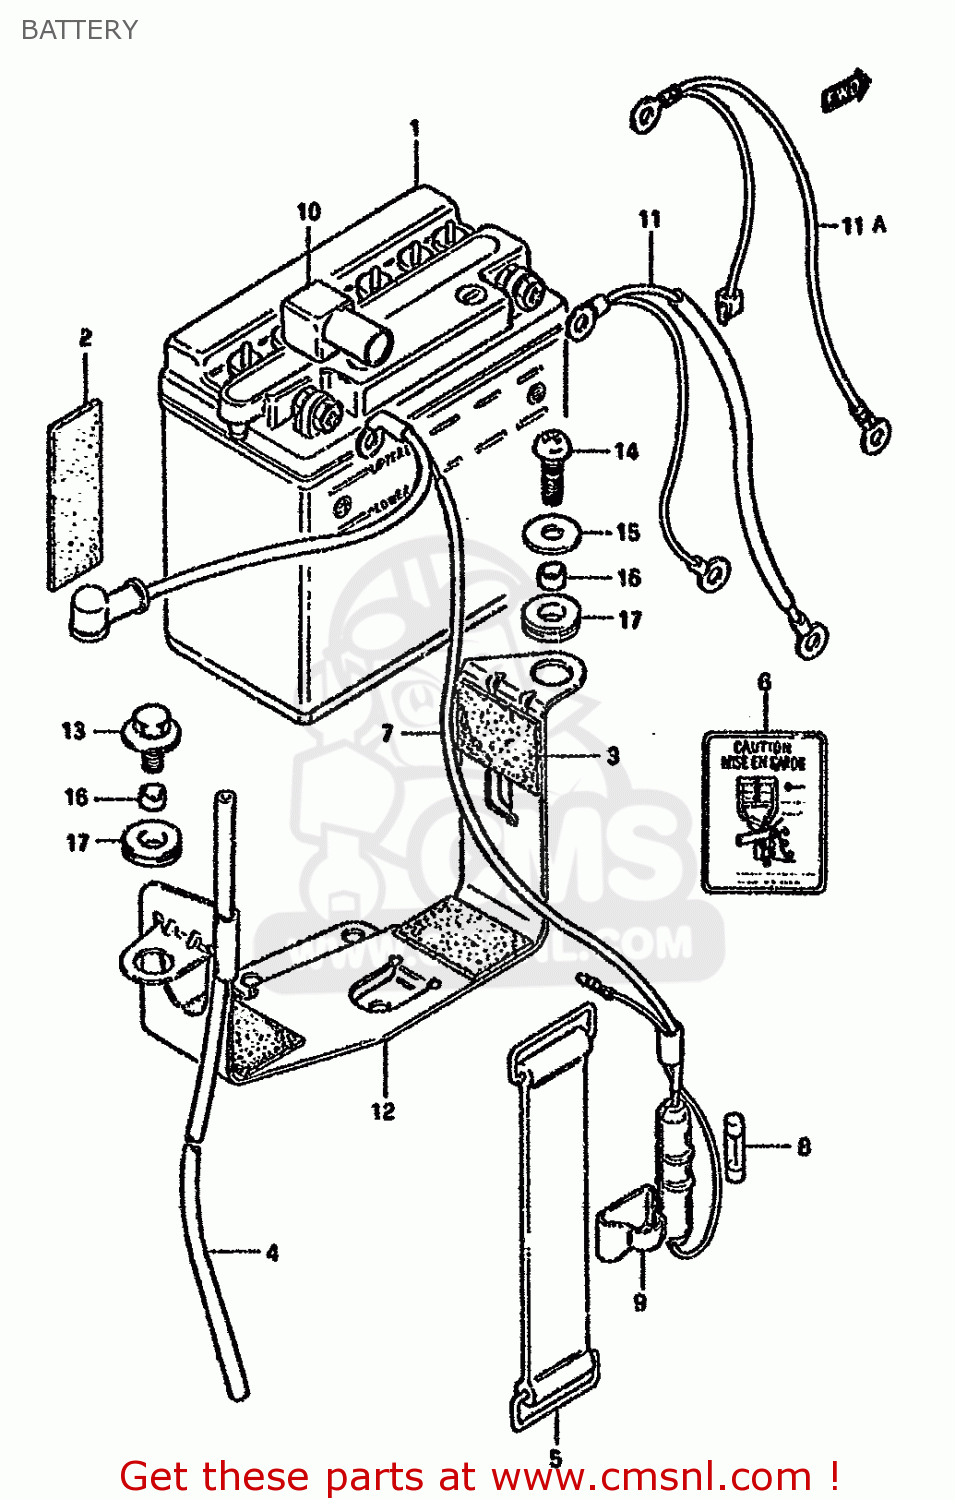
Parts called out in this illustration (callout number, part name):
1	BATTERY ASSY(YB7-A)
2	PROTECTOR(170X95X3.0)
3	PROTECTOR(170X95X3.0)
4	HOSE,BATTERY EXHAUST
5	BAND
6	PLATE,BATTERY CAUTION
7	FUSE CASE AND PLUS CABLE
8	FUSE(15A)
9	HOLDER,FUSE CASE
10	CAP,TERMINAL
11	LEAD WIRE,BATTERY(-)
11A	WIRE,BATTERY MINUS LEAD
12	HOLDER,BATTERY
13	BOLT(6X16)
14	SCREW(6X21)
15	WASHER (6.5X20X1.2)
16	SPACER(6.1X9X7.5)
17	CUSHION
